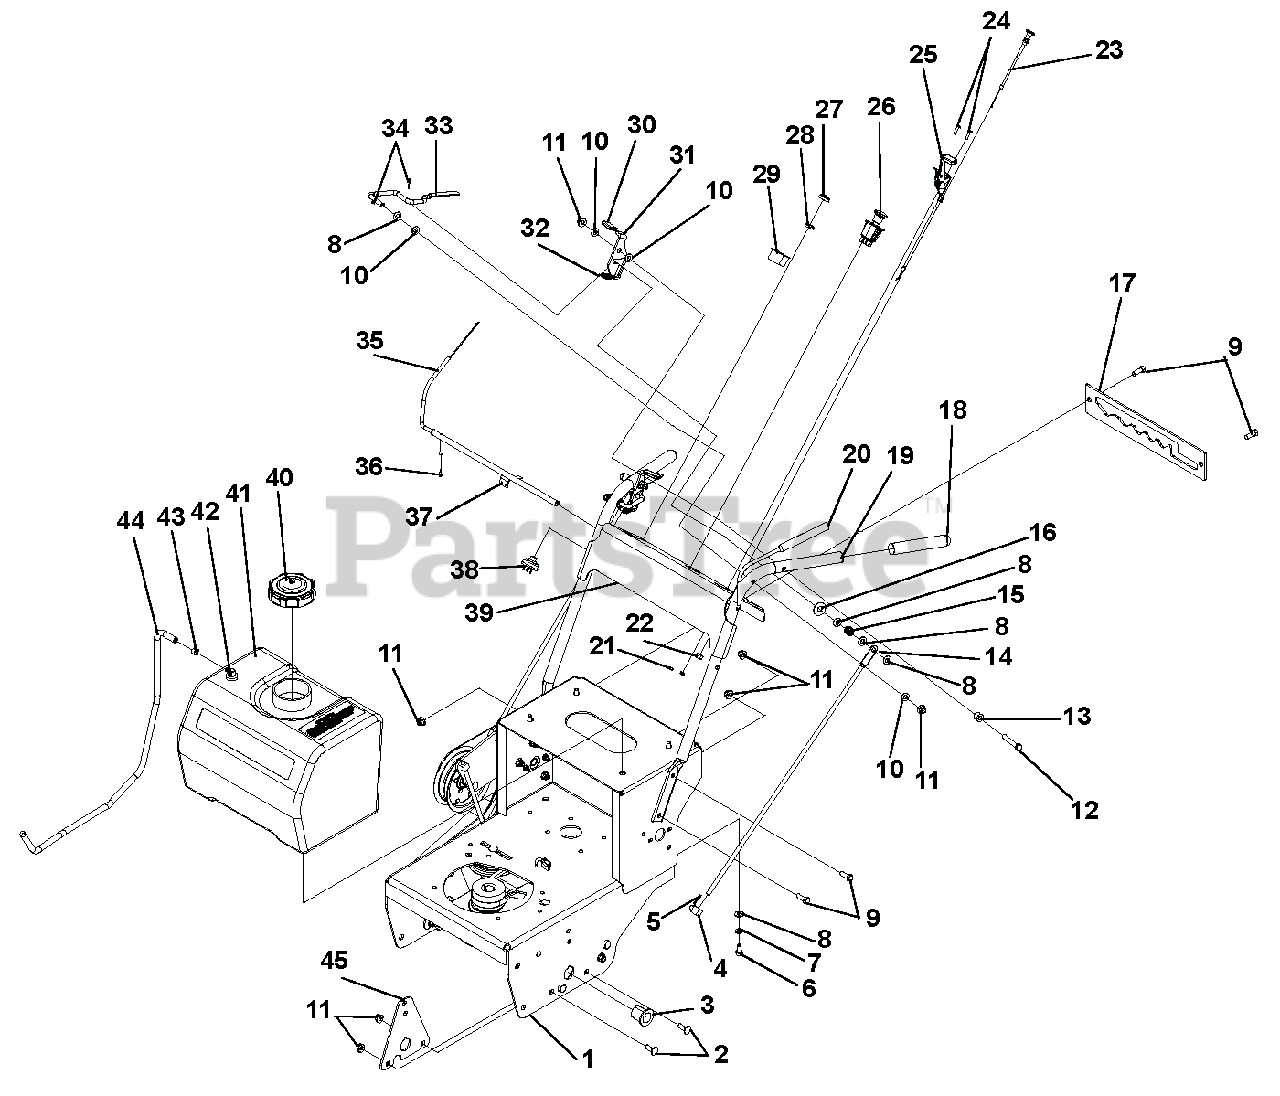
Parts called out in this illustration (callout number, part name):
1	WASP GEAR FRAME W/ DECAL
2	BOLT, 3/8-16X1.00 CRG 5 Y
3	BSHG-FLG 1.010X1.38X1.4X1.65
4	SWIVEL, 3/8-24
5	PIN-HAIR, ENDRIES #25 YWZC
6	BOLT, 3/8-16X.750 HEX 5 Y
7	WASHER, .375 MED SPRG LOCK Y
8	WASHER, .406X.813X.065 FLAT Y
9	BOLT, 3/8-16X1.00 HEX 5 Y
10	WSHR-FL-NY .375X.75X.060
11	@NUT-LK-NYL-FLG .38-16 YWZC
12	BOLT, 3/8-16X2.50 HEX 5 Y
13	BSHG-SLV .391X.688X.52 PM
14	ROD, STEERING
15	SG-COMP .045X.600X.750 WLD7.5
16	@WSHR-FL-STL.50X1.25X.083 YWZC
17	WASP SHIFT LEVER DETENT
18	GRIP, HANDLEBAR
19	CAPLUG, HANDLEBAR
20	LEVER, LH-OP
21	LOCKNUT, 10-24 NYLOC Y
22	NUT, 3/8-24 STD HEX Y
23	CABLE, CHOKE
24	@SCR-MCH 10-24X.75 HWH YWZC
25	CABLE - THROTTLE W/LINER
26	SWITCH - PTO - NMIR
27	CAP - IGNITION SWITCH
28	NUT- PANEL .562-24 GRECO
29	PLUG, HOUR METER
30	GRIP, THUMB LATCH
31	LATCH, LH THUMB
32	SG-TENS .041X.500X1.750
33	LEVER, HAND CONTROL LH
34	PIN, COT .094X.750 EXTP Y
35	LEVER, RH-OP
36	@SCR-TAP 8-32X.50 HWH TR YWZC
37	WELDMENT, PIVOT TUBE
38	KEY SWITCH
39	WASP HANDLEBAR W/ DECALS
40	CAP, FUEL S/O
41	TANK, FUEL W/MOLDED EVR DECAL
42	FITTING, TANK
43	CLAMP, HOSE - 1/2" SPRING
44	HOSE, FUEL 1/4 X 30.00
45	PLATE, AXLE/BEARING MOUNTING
